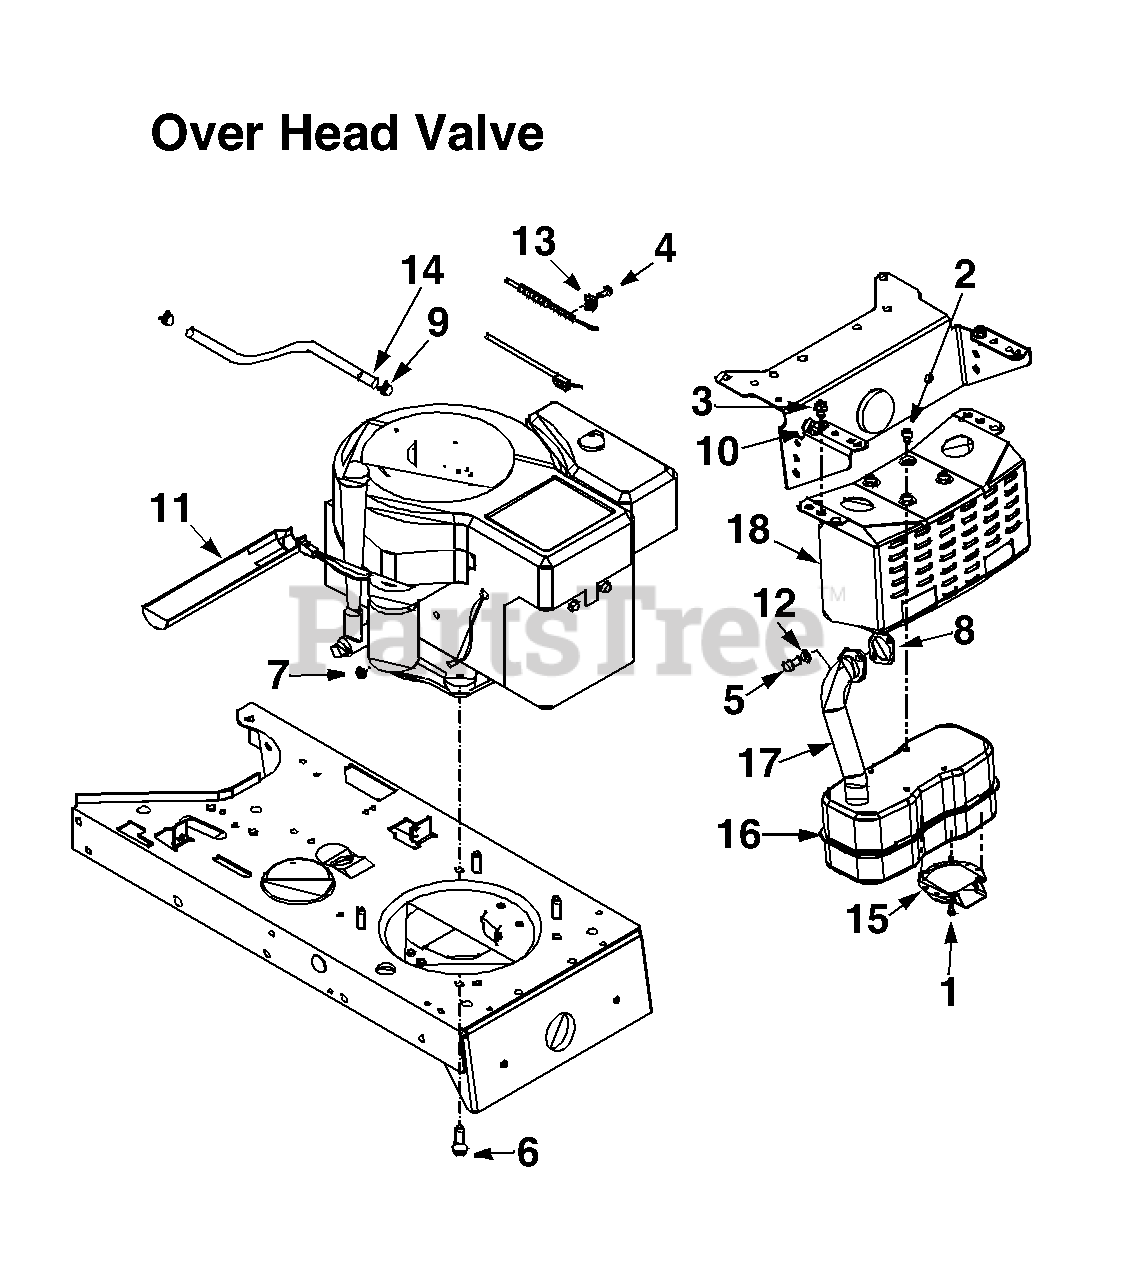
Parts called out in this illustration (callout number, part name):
1	Hex Tap Scr. #8-32 x .38" Lg.
2	Hex TT-Tap Scr. 1/4-20 x .5" Lg.
3	Hex TT-Tap Scr. 5/16-18 x .62"
4	Hex Wash. Scr. #10-32 x .62"
5	Socket Head Scr. 5/16-18 x .62"
6	Hex TT-Tap Scr. 3.8-16 x 1.25"
7	Hex Sems Scr. 1/4-20
8	Gasket
11	Oil Drain Sleeve
12	Lock Washer 5/16 I.D.
13	Casing Clamp
14	Fuel Line
15	Muffler Deflector
16	Muffler
17	Exhaust Pipe
